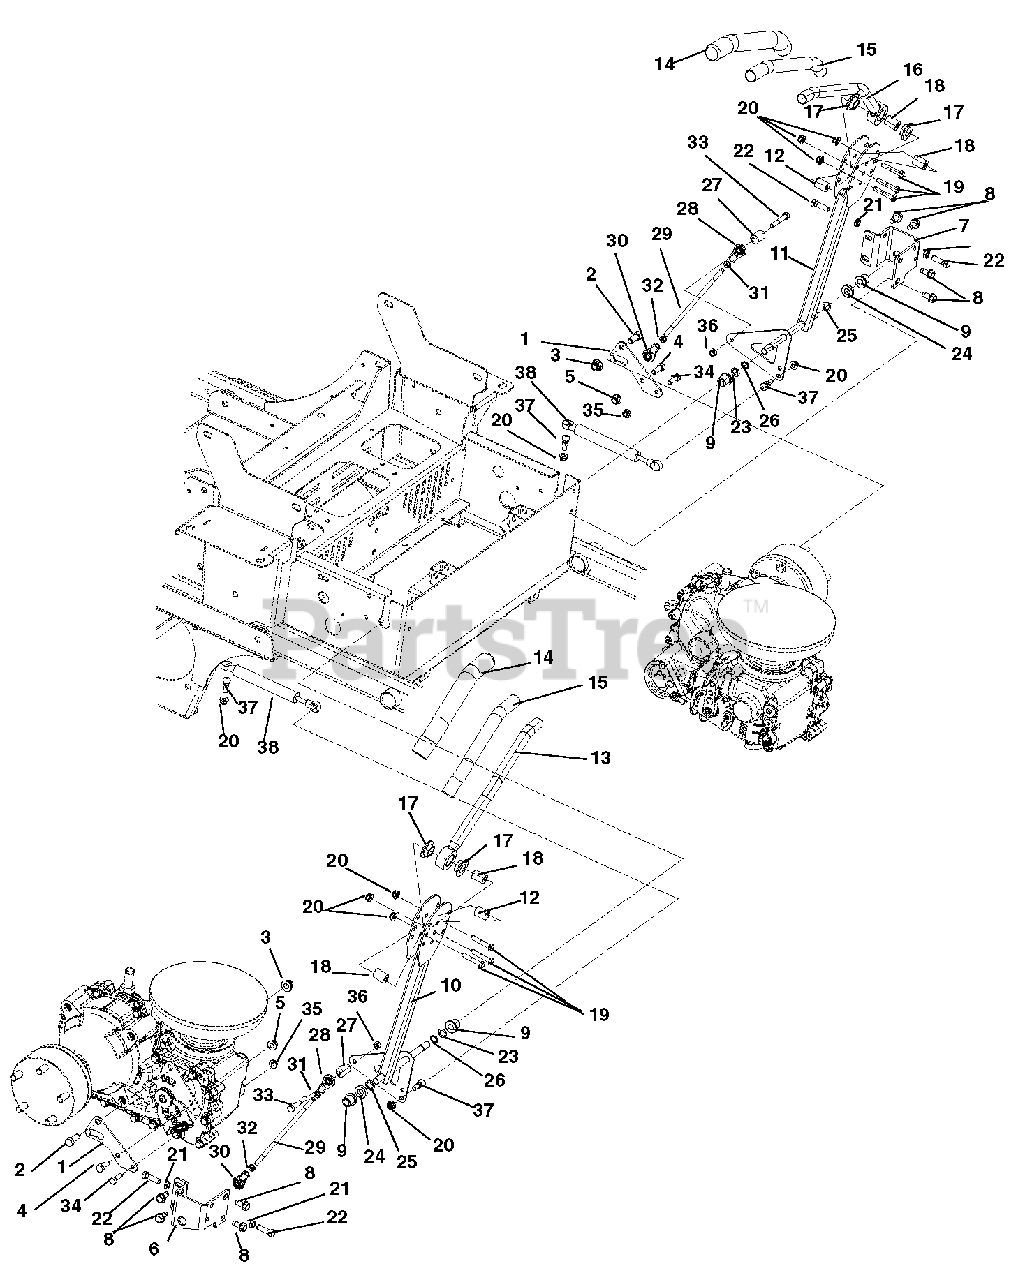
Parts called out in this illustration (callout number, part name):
1	Bracket, Control Mounting
2	Bolt, Hex .44-14 x 1.00 Grade 5
3	Nut, Locking-Nylon-Flange .44-14
4	Bolt, Hex .38-16 x 1.00 Grade 5
5	Nut, Locking-Nylon-Flange .38-16
6	Bracket, Right Hand Control Stop
7	Bracket, Left Hand Control Stop
8	Screw, Tapping .38-16 x .75 Hex Washer Head
9	Bushing, Flange .515 x .750 x .745 x 1.00 Nylon
10	Weldment, Right Hand Control Arm
11	Weldment, Left Hand Control Arm
12	Bushing, Eccentric .31 x .75 x .97
13	Handle Weldment Right Hand
14	Grip, Handlebar 1.00 x 1.38 x 11.3
15	Tube, .88ID x 1.00OD x 10.75
16	Handle Weldment Left Hand
17	Bushing, Flange .762 x 1.48 x .44 Nylon
18	Spacer .328 x .76 x 1.01
19	Bolt, Hex .31-18 x 1.75 Grade 5
20	Nut, Locking-Nylon-Flange .31-18
21	Nut, Hex-Jam .375-16
22	Bolt, Hex .38-16 x 1.25 Grade 5
23	Washer, Flat-Steel .520 x .810 x .033
24	Spacer .531 x 1.00 x .195
25	Wave Washer .531 x .781 x .125FH
26	Ring, Retaining-External .500 x .050
27	Eccentric
28	Alingaball, 5/16 Right Hand Thread
29	Rod, Steering
30	Alingaball, 5/16 Left Hand Thread
31	Nut, Jam .31-24
32	Nut, Jam Left Hand .31-24
33	Bolt, Hex .31-18 x 2.00 Grade 5
34	Bolt, Hex .31-18 x 1.00 Grade 5
35	Nut, Locking-Top-Flange .31-18
36	Nut, Locking-Center .31-18
37	Stud, Ball
38	Damper
